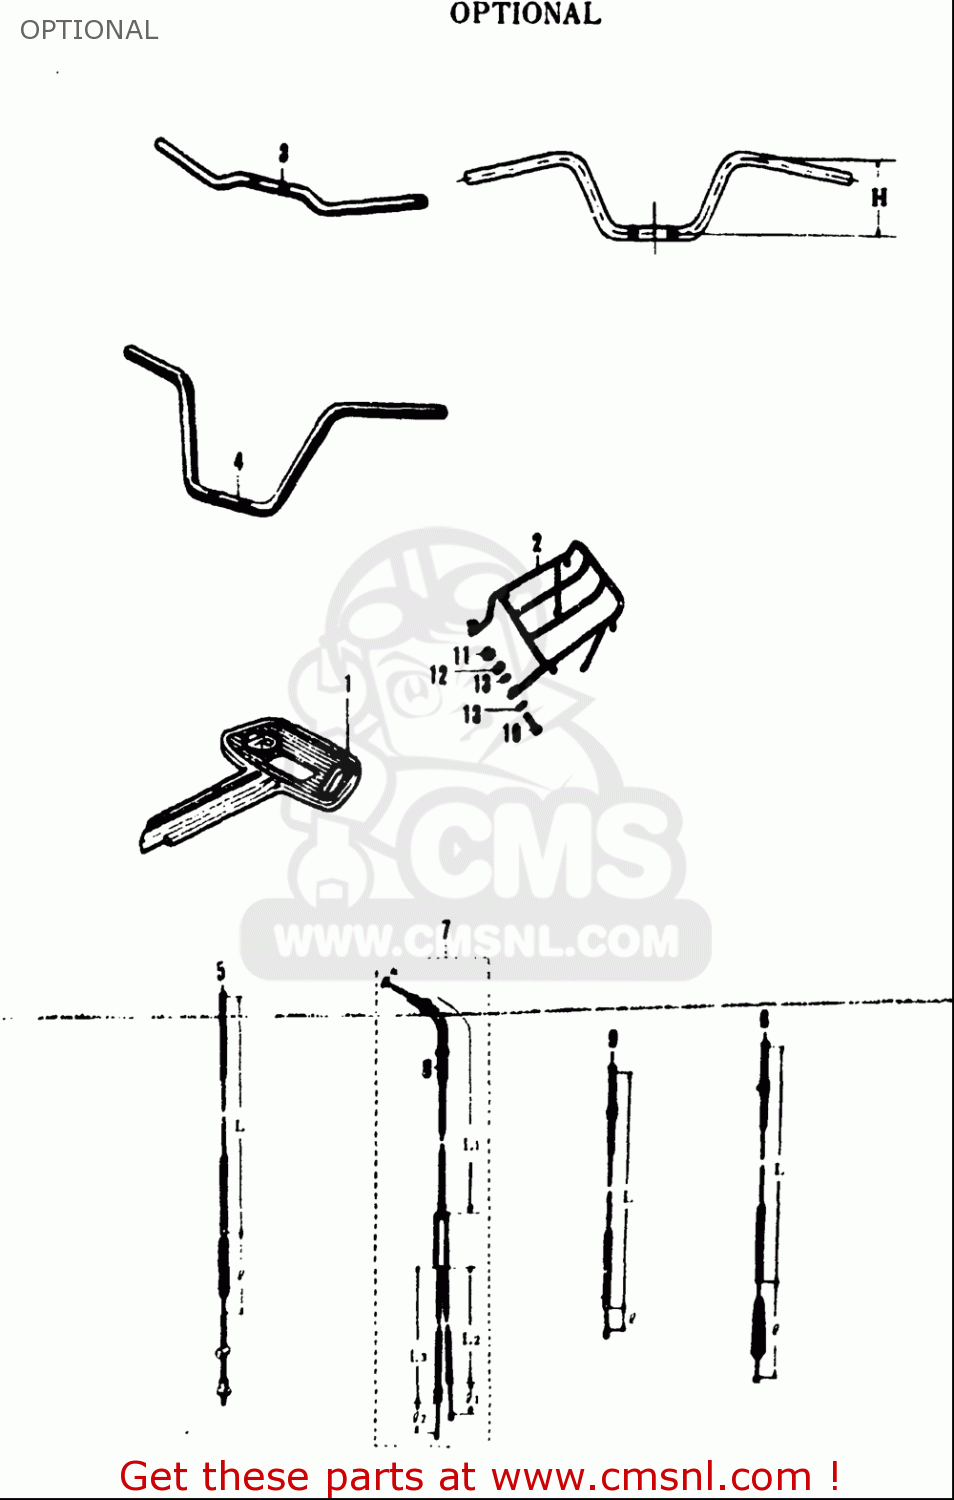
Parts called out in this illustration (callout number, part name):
5	CABLE ASSY,FR BRAKE
7	CABLE,THROTTLE (0; FOR WESTERN HANDLEBAR L98) L2=250(9.84) L3=3
11	NUT
12	WASHER,LOCK
